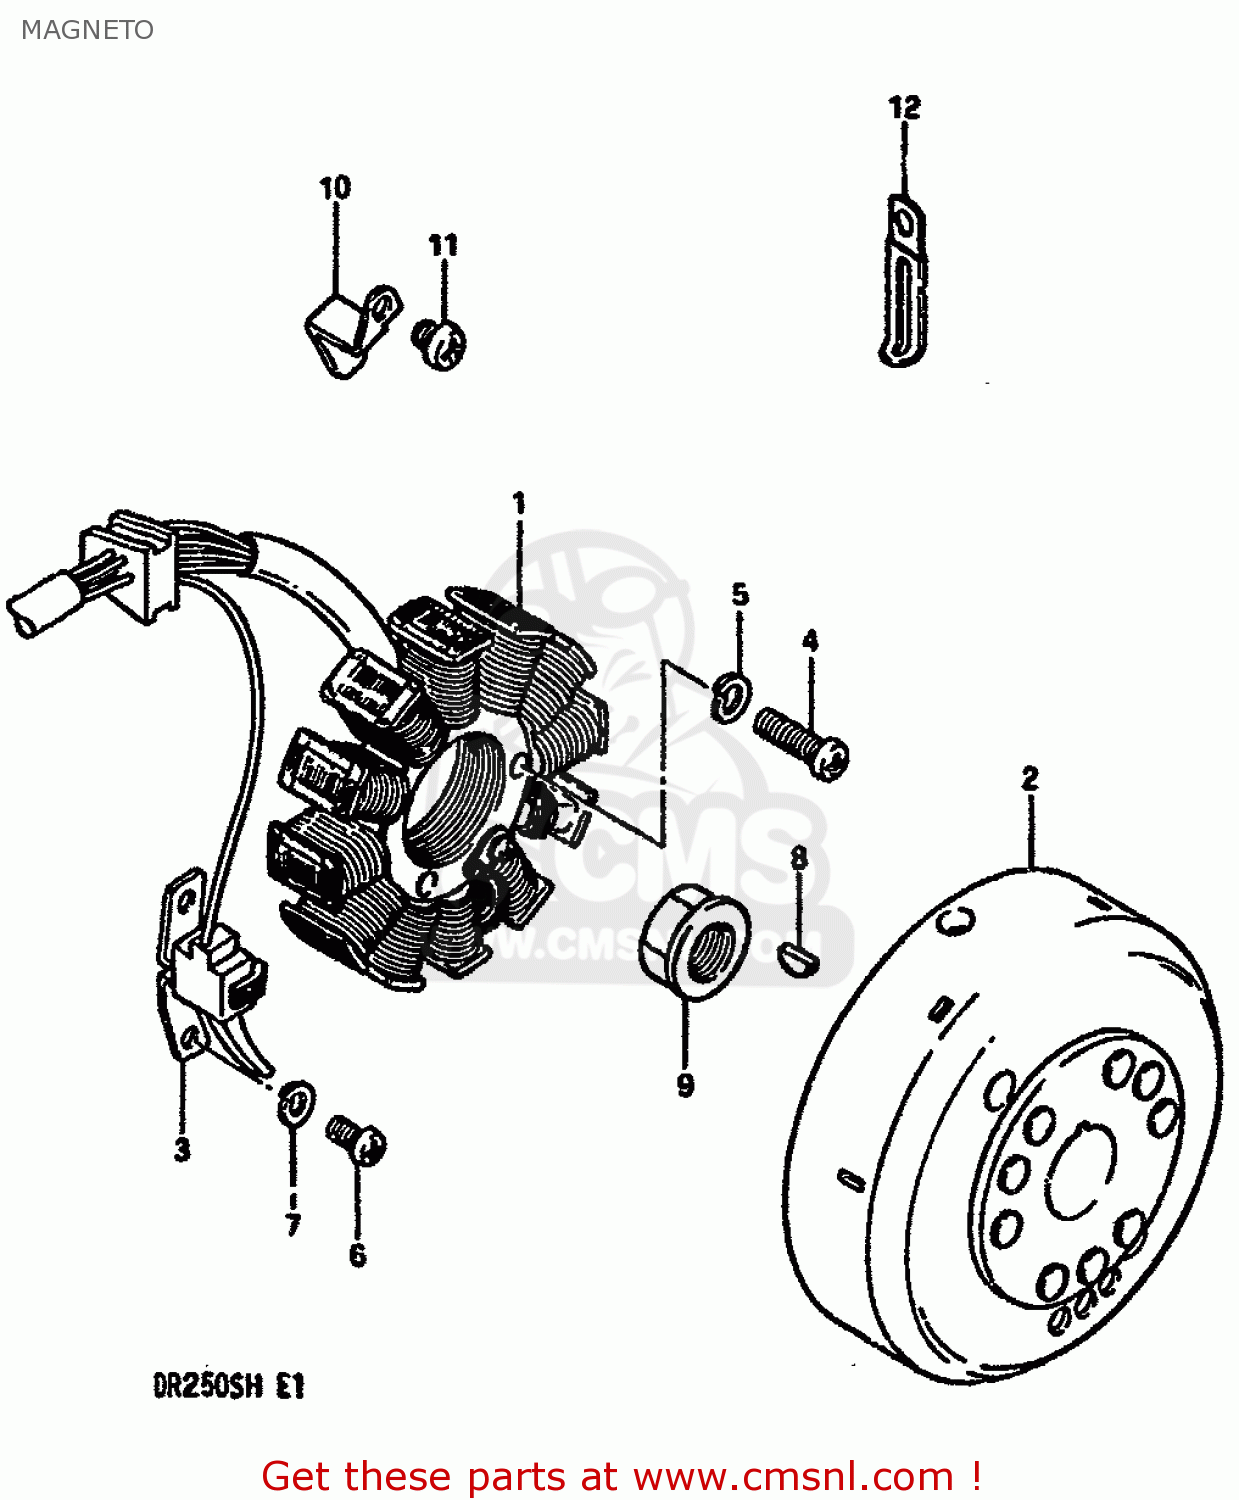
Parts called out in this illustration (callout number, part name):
1	STARTER ASSY
2	ROTOR,FLYWHEEL
3	COIL,PICK UP
4	SCREW
5	WASHER,LOCK
6	SCREW
7	LOCK WASHER
8	KEY 4MM
9	NUT,GENERATOR ROTOR
10	CLAMP,MAGNETO LEAD WIRE
11	SCREW
12	CLAMP L:35
